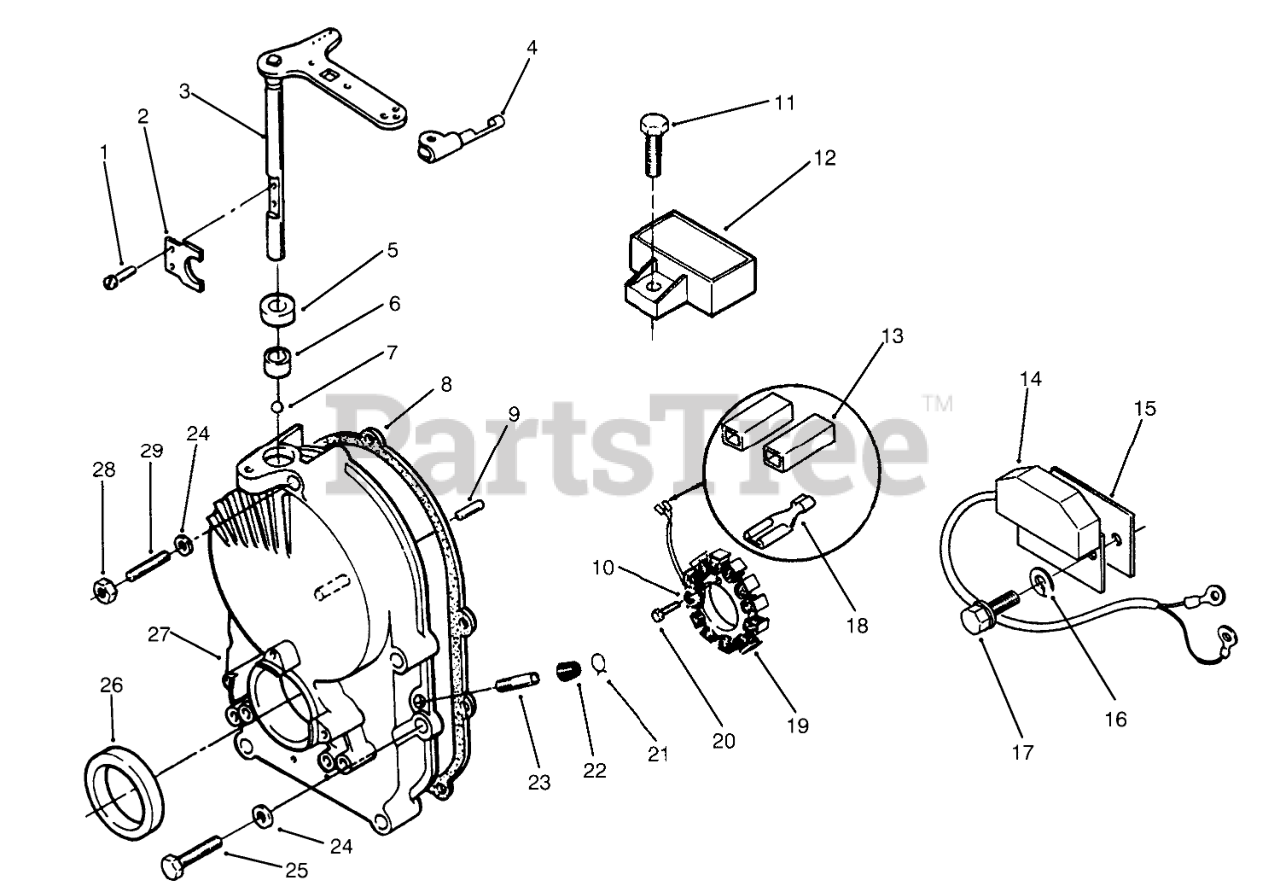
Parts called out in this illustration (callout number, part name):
1	SCREW-PAN HD
3	SHAFT AND ARM
6	BEARING
8	Gasket
9	PIN-DOWEL
10	WASHER-LOCK
11	SCREW-HWH
12	REGULATOR
13	Body-Terminal Conn. Kit (Incl. Ref. #18)
14	CONTROL-IGNITION
15	INSULATOR-IGN MODULE
16	WASHER-LOCK
17	Bolt
18	TERMINAL
19	Stator (Incl. Ref. #18)
20	Screw-HH
21	CLAMP
22	CAP-FUEL OUTLET
23	TUBE-PORT, VACUUM
24	WASHER
25	HEX-HEAD CAP SCREW
27	Kit-Gearcase (Incl. Ref. #1-3, 5-7, 9, 21-23 & 26)
28	NUT-GEAR COVER
29	STUD-GEAR COVER
